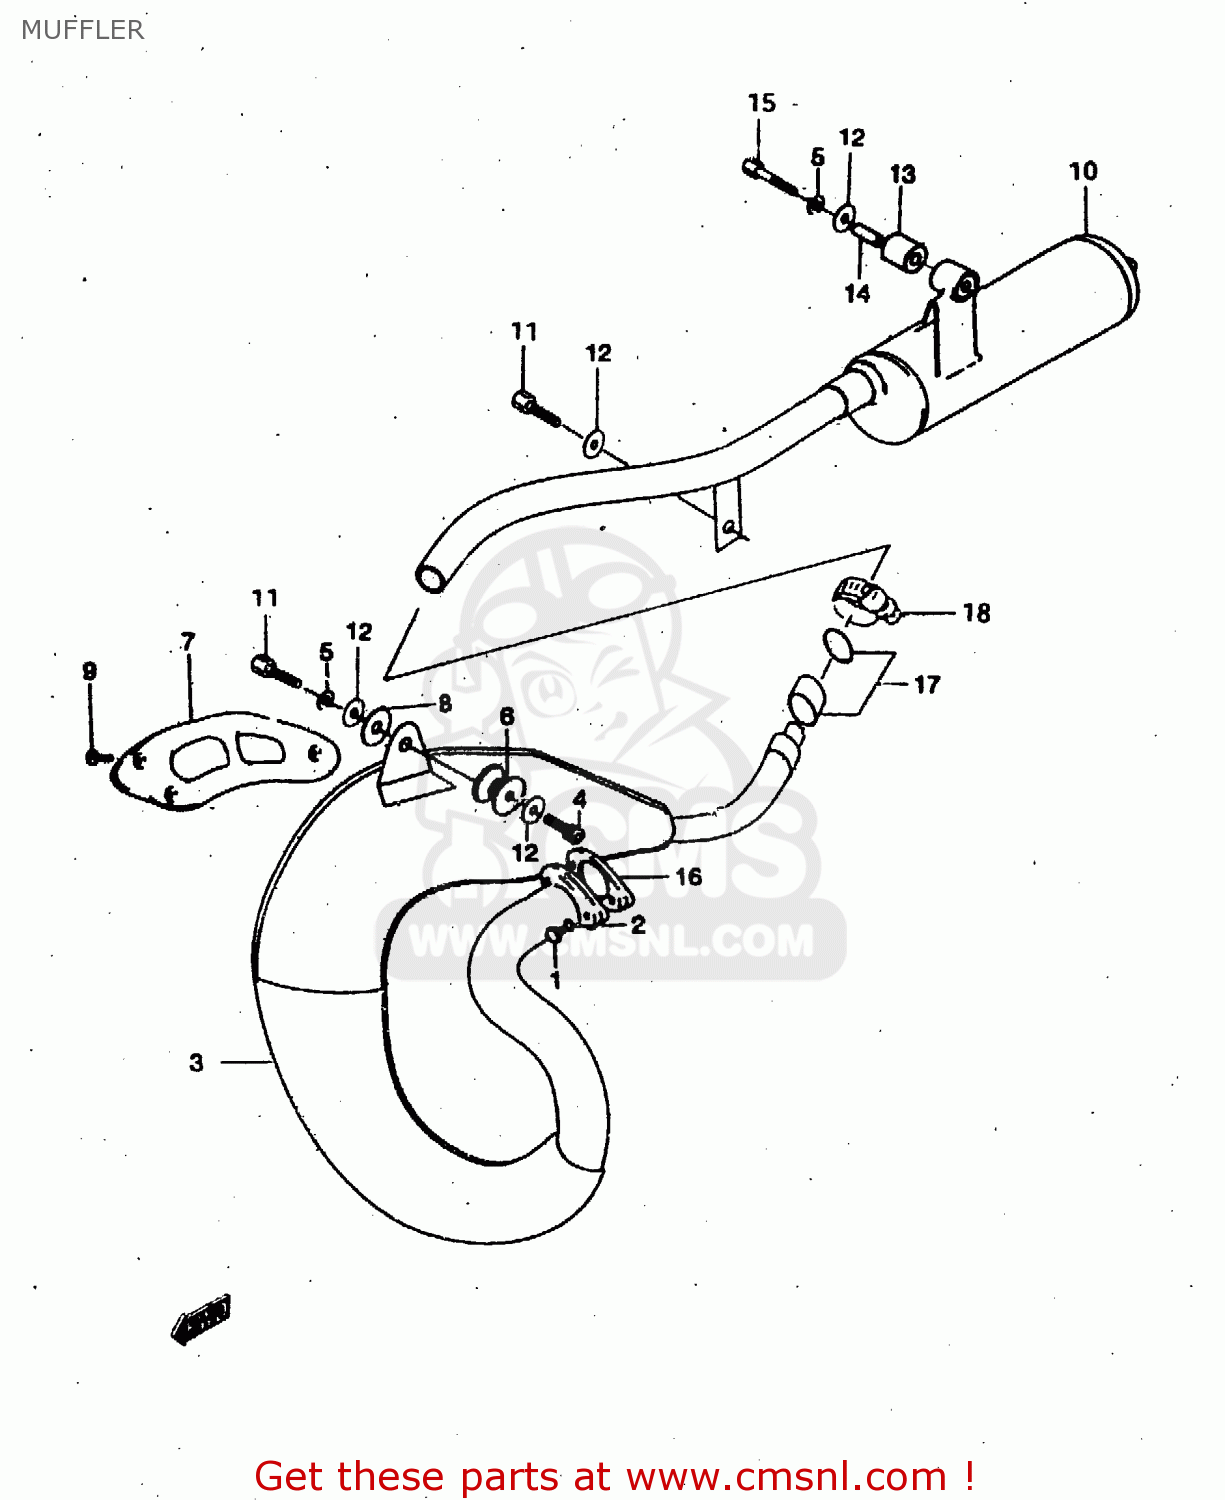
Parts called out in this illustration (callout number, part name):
1	BOLT,CRKCASE,R
2	LOCK WASHER
3	MUFFLER ASSY
4	PLUG
5	LOCK WASHER
6	BUSH
7	GUARD
8	KLINGERIT
9	BOLT
10	MUFFLER ASSY
11	BOLT
12	WASHER (8.5X24X2.3)
13	CUSHION
14	SPACER
15	BOLT
16	GASKET,EXHAUST PIPE (NAS)
17	CONNECTOR,MUFFLER
18	CLAMP
